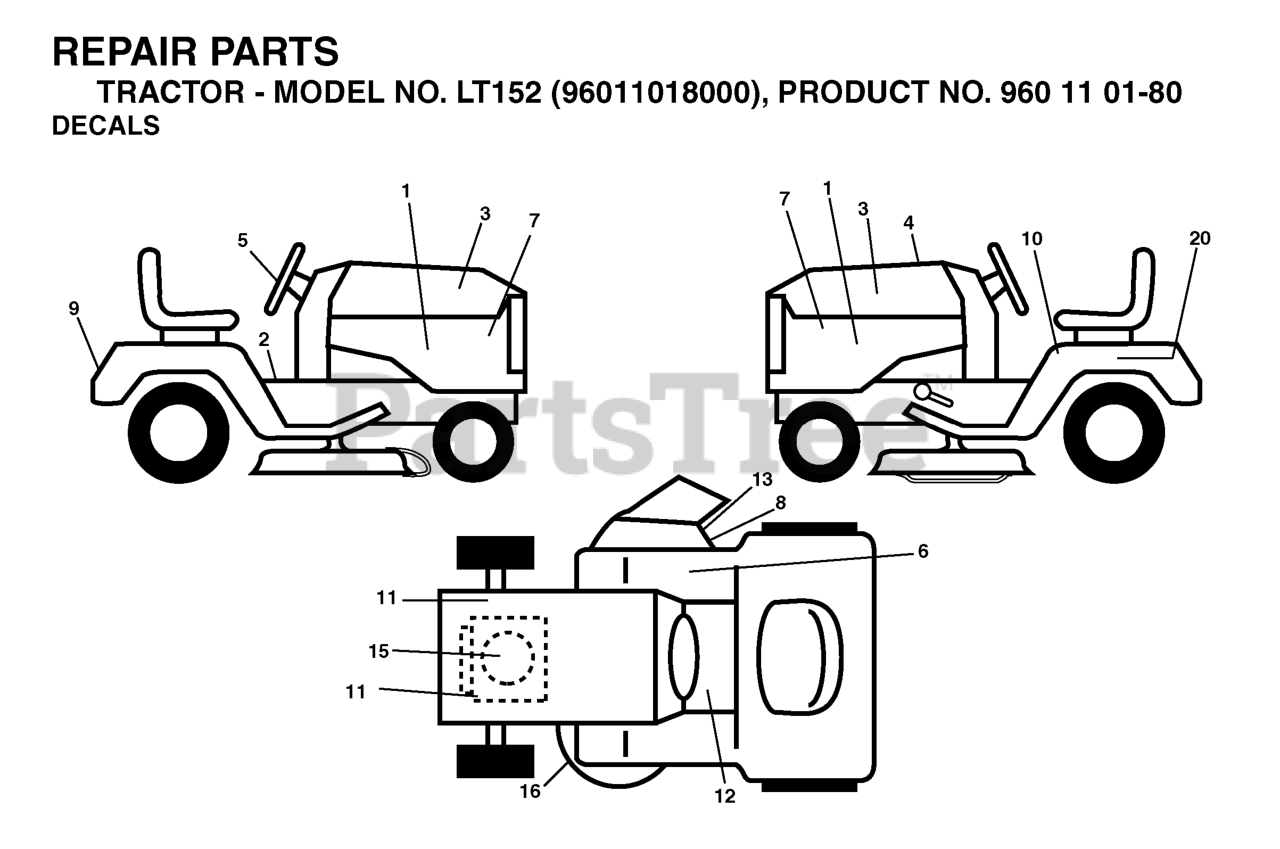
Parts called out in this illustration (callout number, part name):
2	DECAL PARK BRAKE
5	DECAL.STEERING.HUSQ.BLUE
6	Decal, Fender 100 DB/CE
7	DECAL.HOOD.HUSQVARNA.INTERNATI
8	DECAL.INTERNATIONL.CUTFINGER
10	LABEL
12	DECAL
13	DECAL, DEFLECT WARNING
15	DECAL
16	DECAL V BELT SCHEMATIC
20	DECAL BTRY SYMBOLS
